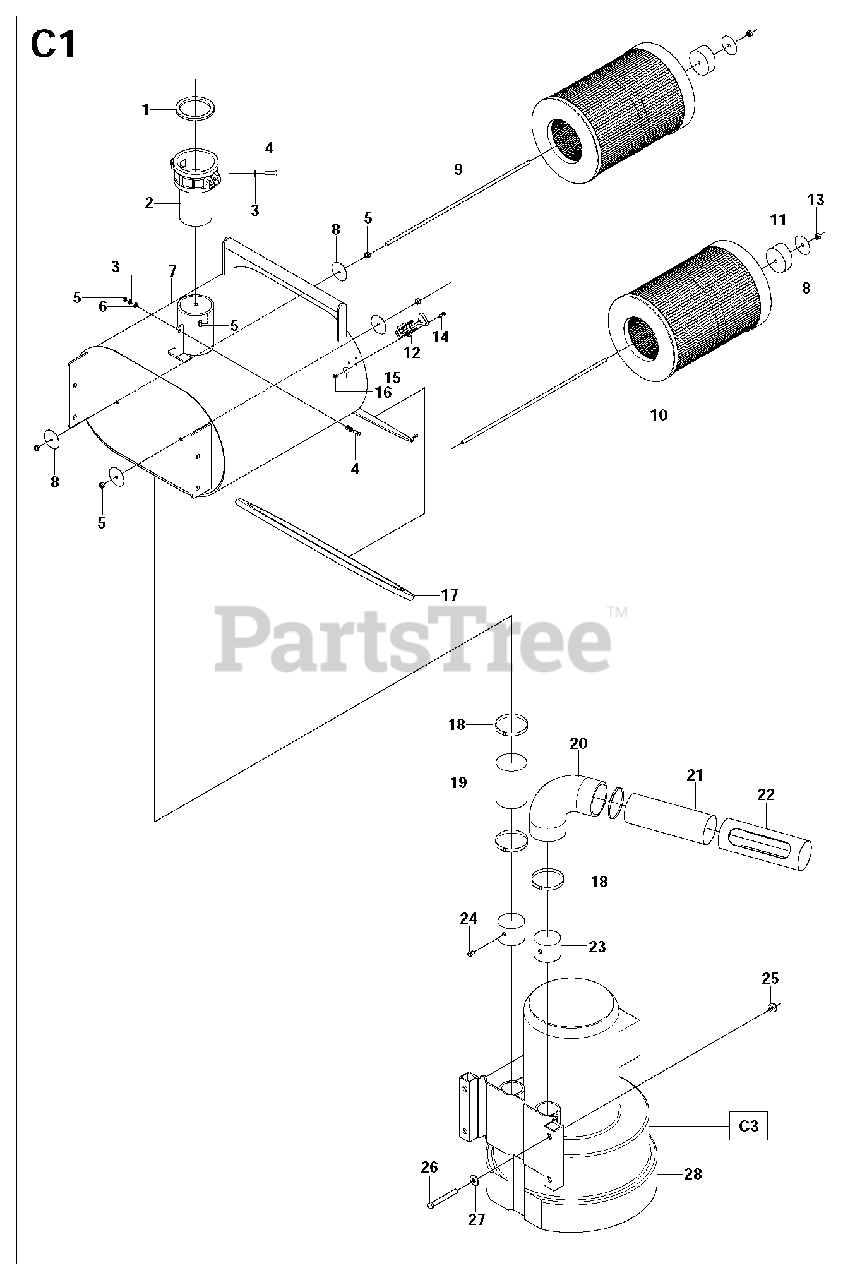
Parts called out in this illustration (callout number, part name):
3	WASHER
5	HEXAGON LOCKING NUT
15	HEXAGON NUT
17	WASHER
18	HEXAGON LOCKING NUT
27	WASHER
